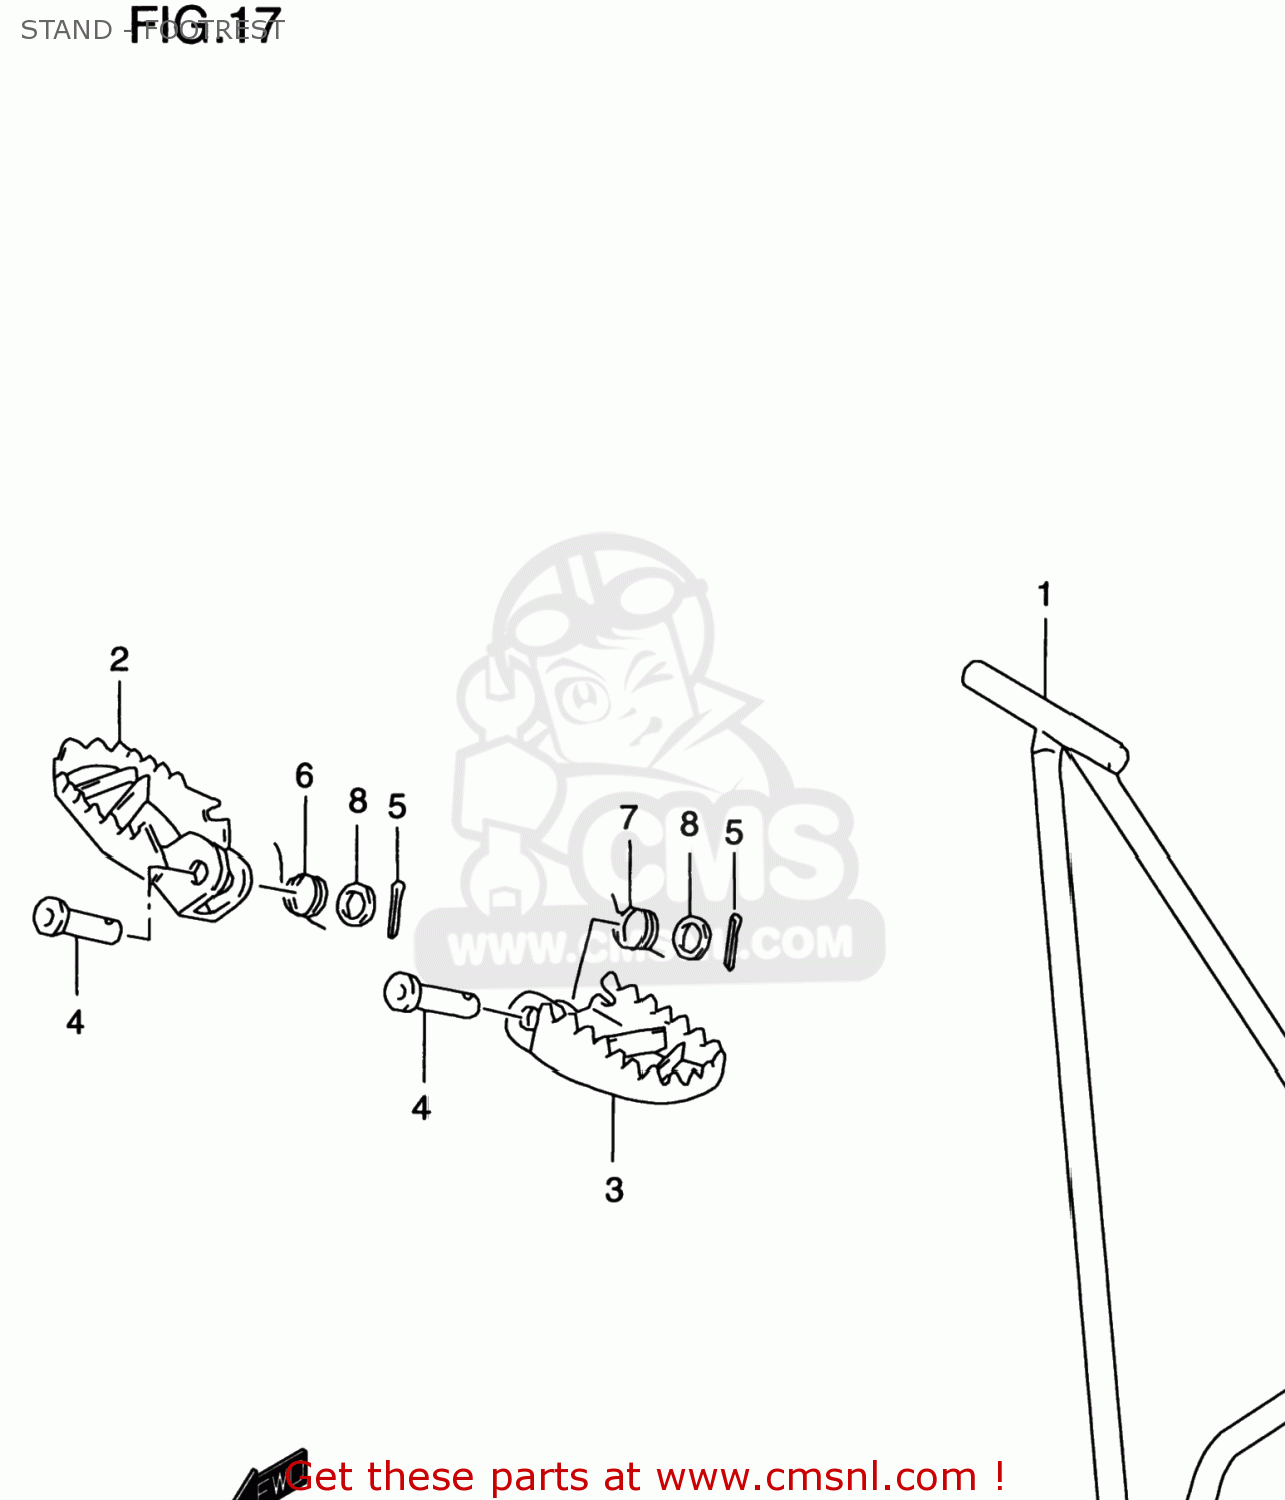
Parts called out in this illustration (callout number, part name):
1	STAND
2	FOOTREST,R
3	FOOTREST,L
4	PIN(10X41.5)
5	PIN 25X20
6	SPRING
7	SPRING
8	WASHER
